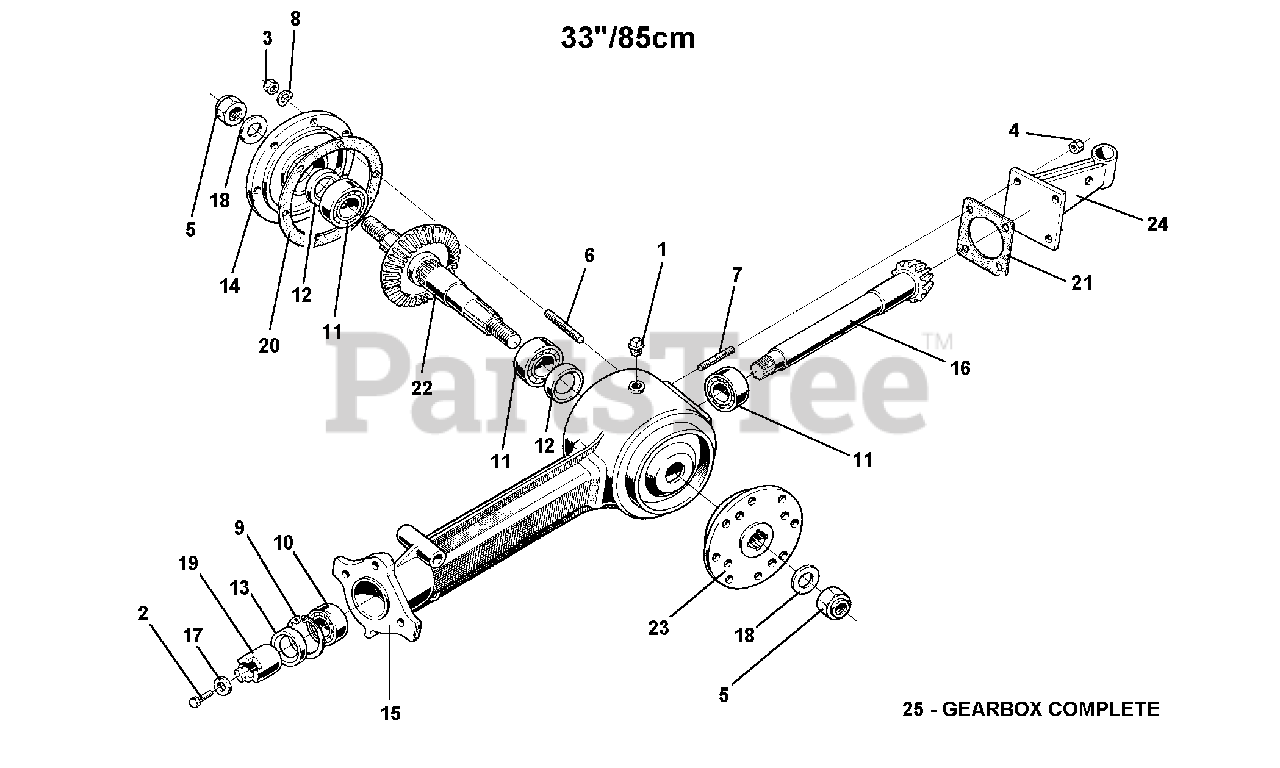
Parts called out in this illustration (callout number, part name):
1	PLUG 1/4 GAS
2	SCREW M6 X 20
3	NUT, SELF LOCKING M8
5	NUT, SELF LOCKING M18 X 1.5 STD
6	STUD M8 X 38 X 16 X 16 8G
7	STUD M10 X 37 X 19 X 15 8G
8	WASHER, LOCK 8.4
9	CIRCLIP, INTERN D 52
10	BEARING 25 X 52 X 15 6205
11	BEARING 30 X 62 X 16 6206
12	SEAL, OIL 30 X 52 X 10 STANDARD
13	SEAL, OIL 40 X 52 X 7 STANDARD
15	ROTARY HOE CENTRAL ASSEMBLY
17	WASHER 7 X 25 X 4
18	WASHER, HOE LOCK
19	ROTARY HOE COUPLING
20	COVER GASKET
21	COVER GASKET
23	BLADE HOLDER FLANGE
25	GEARBOX COMPLETE
